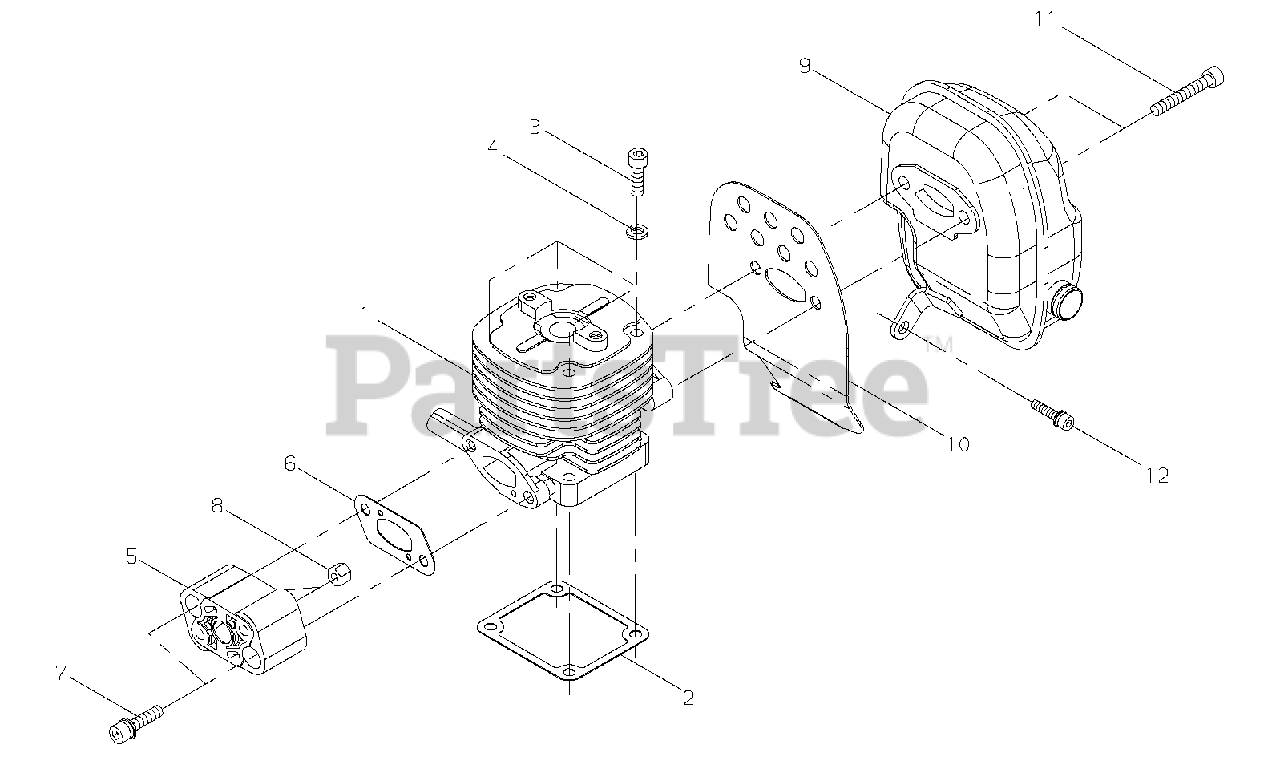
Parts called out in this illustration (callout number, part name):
1	CYLINDER
2	GASKET, CYLINDER
3	SCREW - 5X25
4	LOCKWASHER - 5
5	INSULATOR
6	GASKET
7	SCREW - 5X25
8	NUT
9	MUFFLER
10	GASKET
11	SCREW - 6X25
12	SCREW - 5X12
